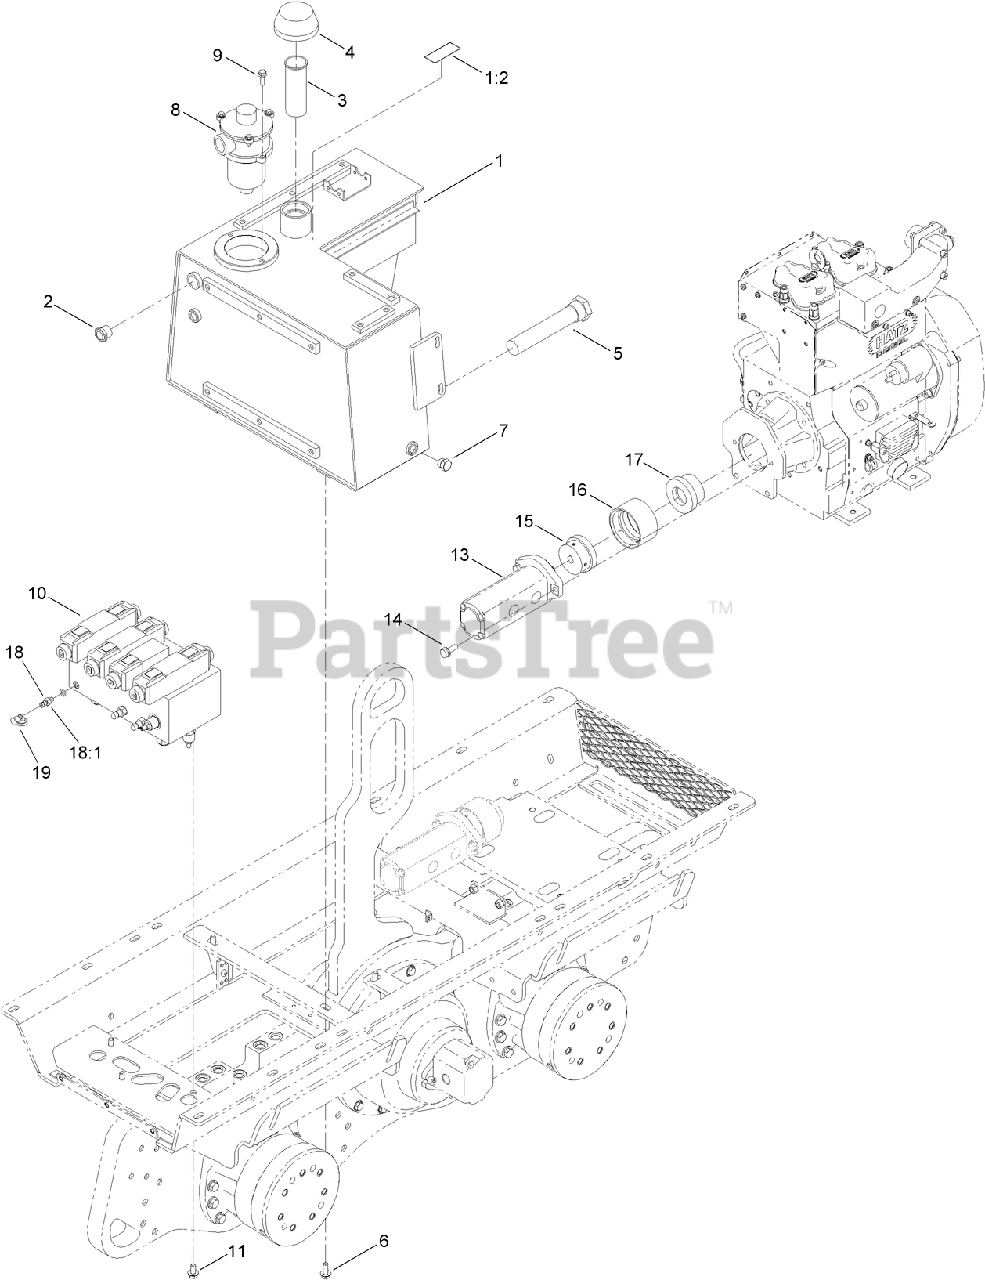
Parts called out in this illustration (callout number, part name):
1	HYD TANK ASM
1:2	DECAL-CAUTION, HYD FLUID
2	GLASS SIGHT ASM
3	BASKET-STRAINER
4	BREATHER-HYD
5	STRAINER
6	SCREW-HHF
8	RETURN FILTER ASM
9	SCREW-HHF
10	HYD MANIFOLD ASM
11	SCREW-HHF
13	HYD TRIPLE GEAR PUMP ASM
14	SCREW-HHF
15	COUPLING
16	SLEEVE-COUPLING
17	COUPLING
18	FITTING-QUICK
18:1	O-RING
19	CAP-DUST
